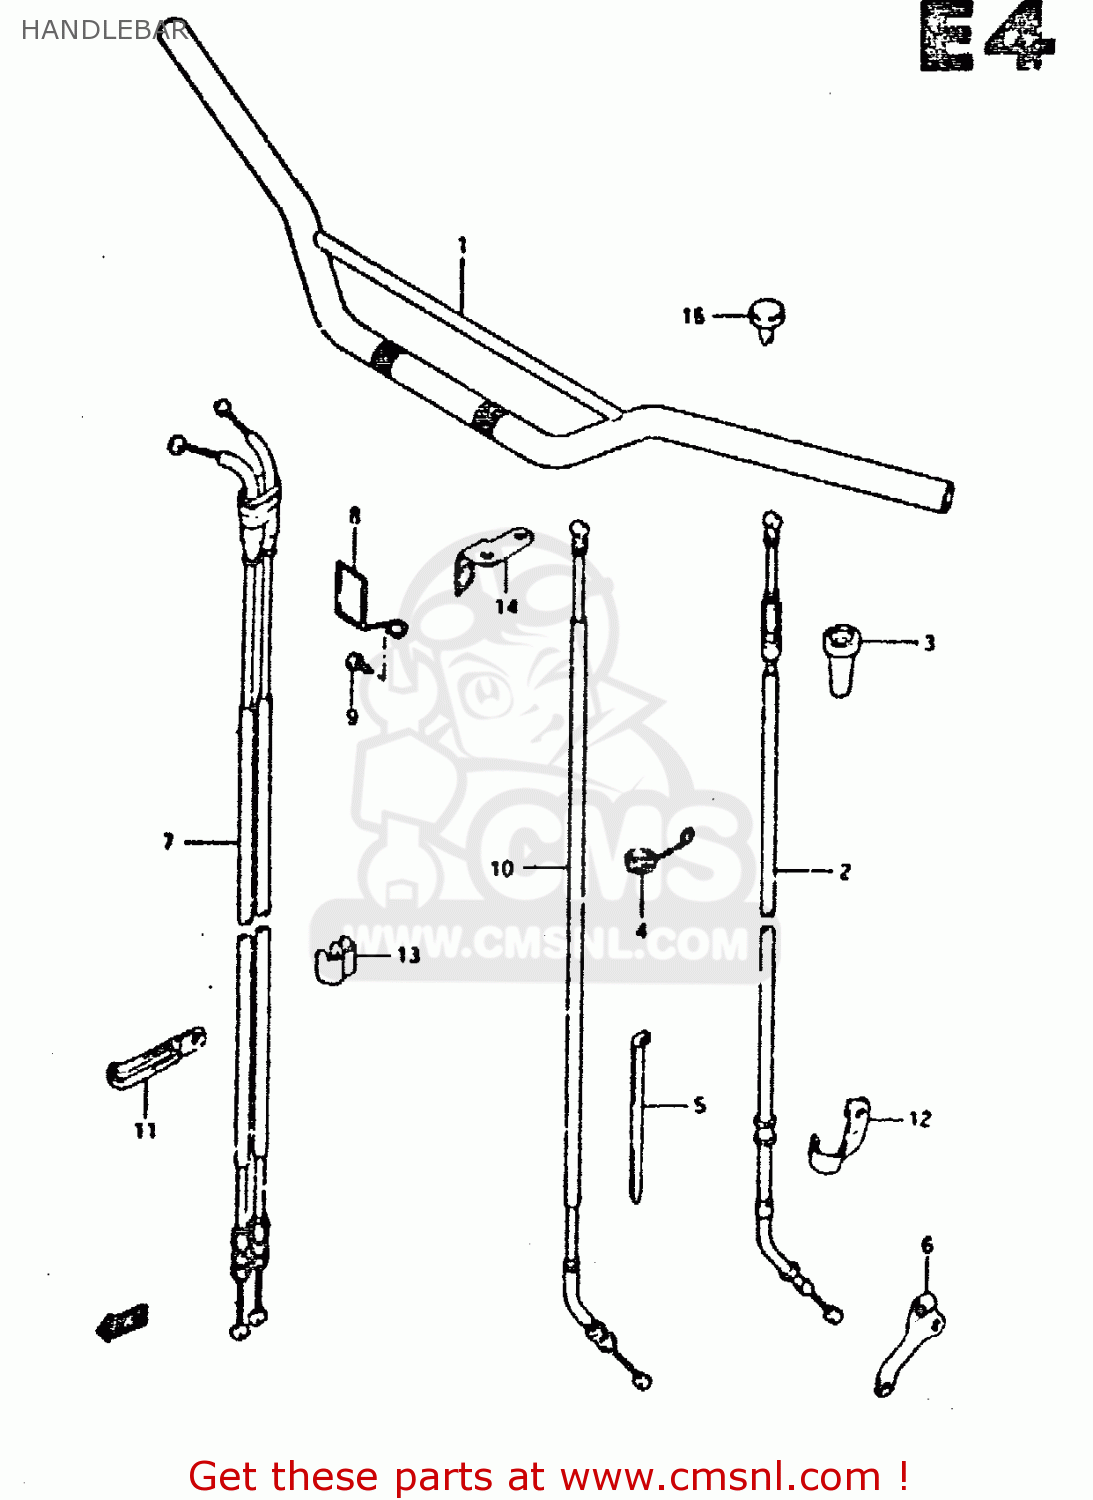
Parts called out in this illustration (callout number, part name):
1	HANDLEBAR
2	CABLE ASSEMBLY,CLUTCH
3	BOOT,CLUTCH CABLE
4	GUIDE,CLUTCH CABLE
5	CLAMP(L:145)
6	STOPPER,CLUTCH CABLE
7	CABLE SET,THROTTLE
8	GUIDE,CABLE
9	BOLT
10	CABLE ASSY,DECOMP
11	CLAMP
12	CLAMP,CLUTCH CABLE
13	CLIP
14	GUIDE,CABLE
15	CAP(OD:14)
